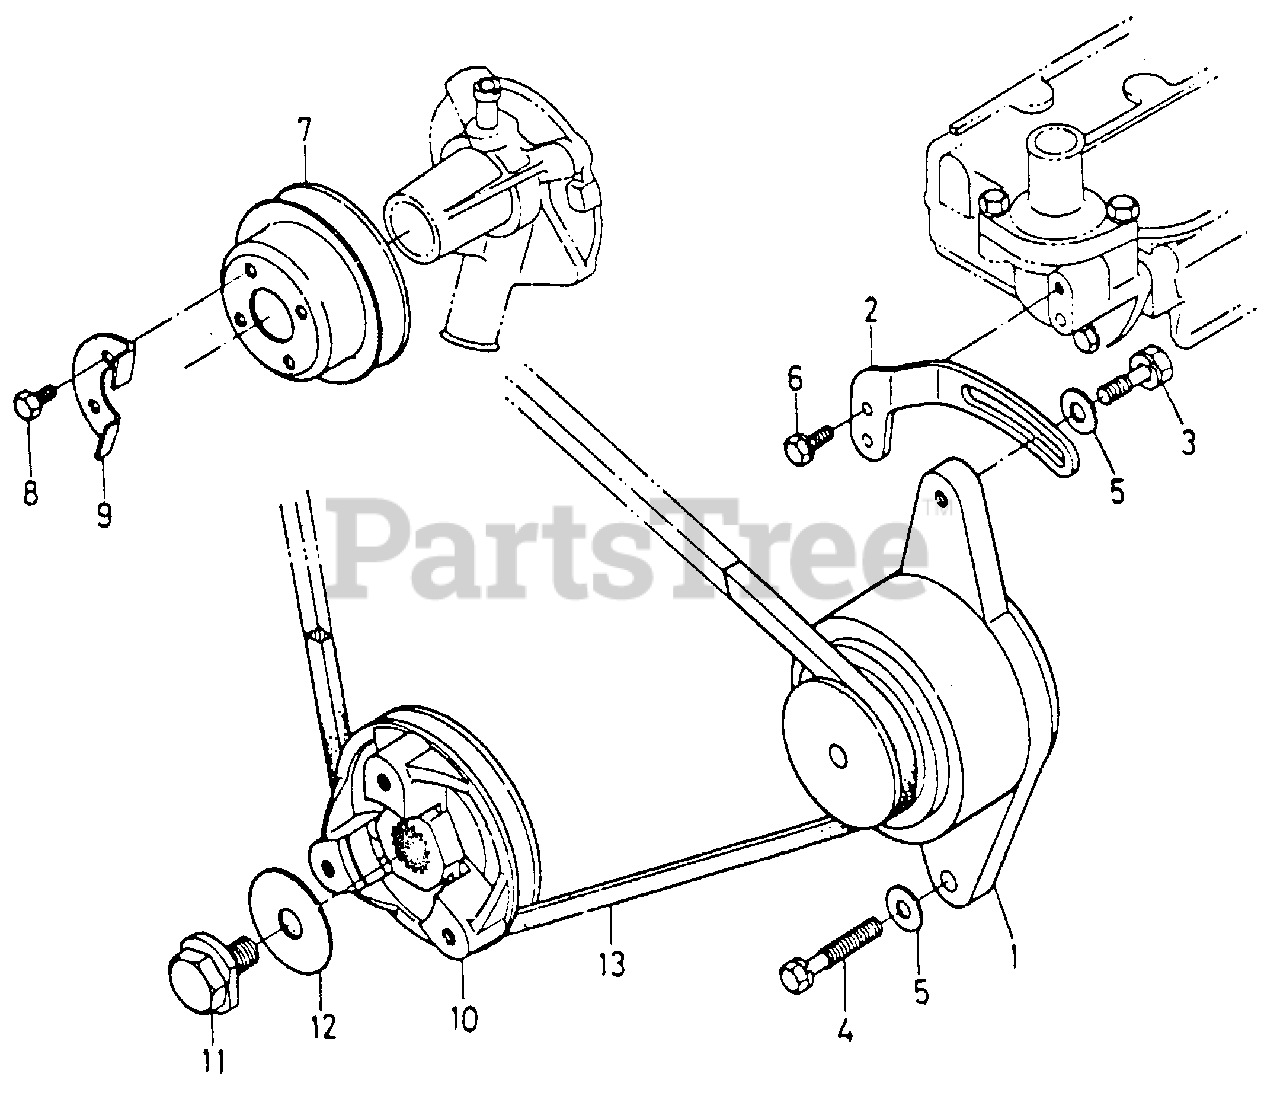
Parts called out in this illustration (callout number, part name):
1	Alternator
2	Support, Alternator
3	Bolt, M8 X 25 Class 8.8 w/Washer
5	Washer, 8.8 X 17 X 1.6MM
6	Bolt, M6 X 16 Class 8.8 w/Washer
7	Pulley, Water Pump
8	Bolt, M6 X 12 Class 8.8
10	Pulley, Alternator Drive
12	Washer, Plain
